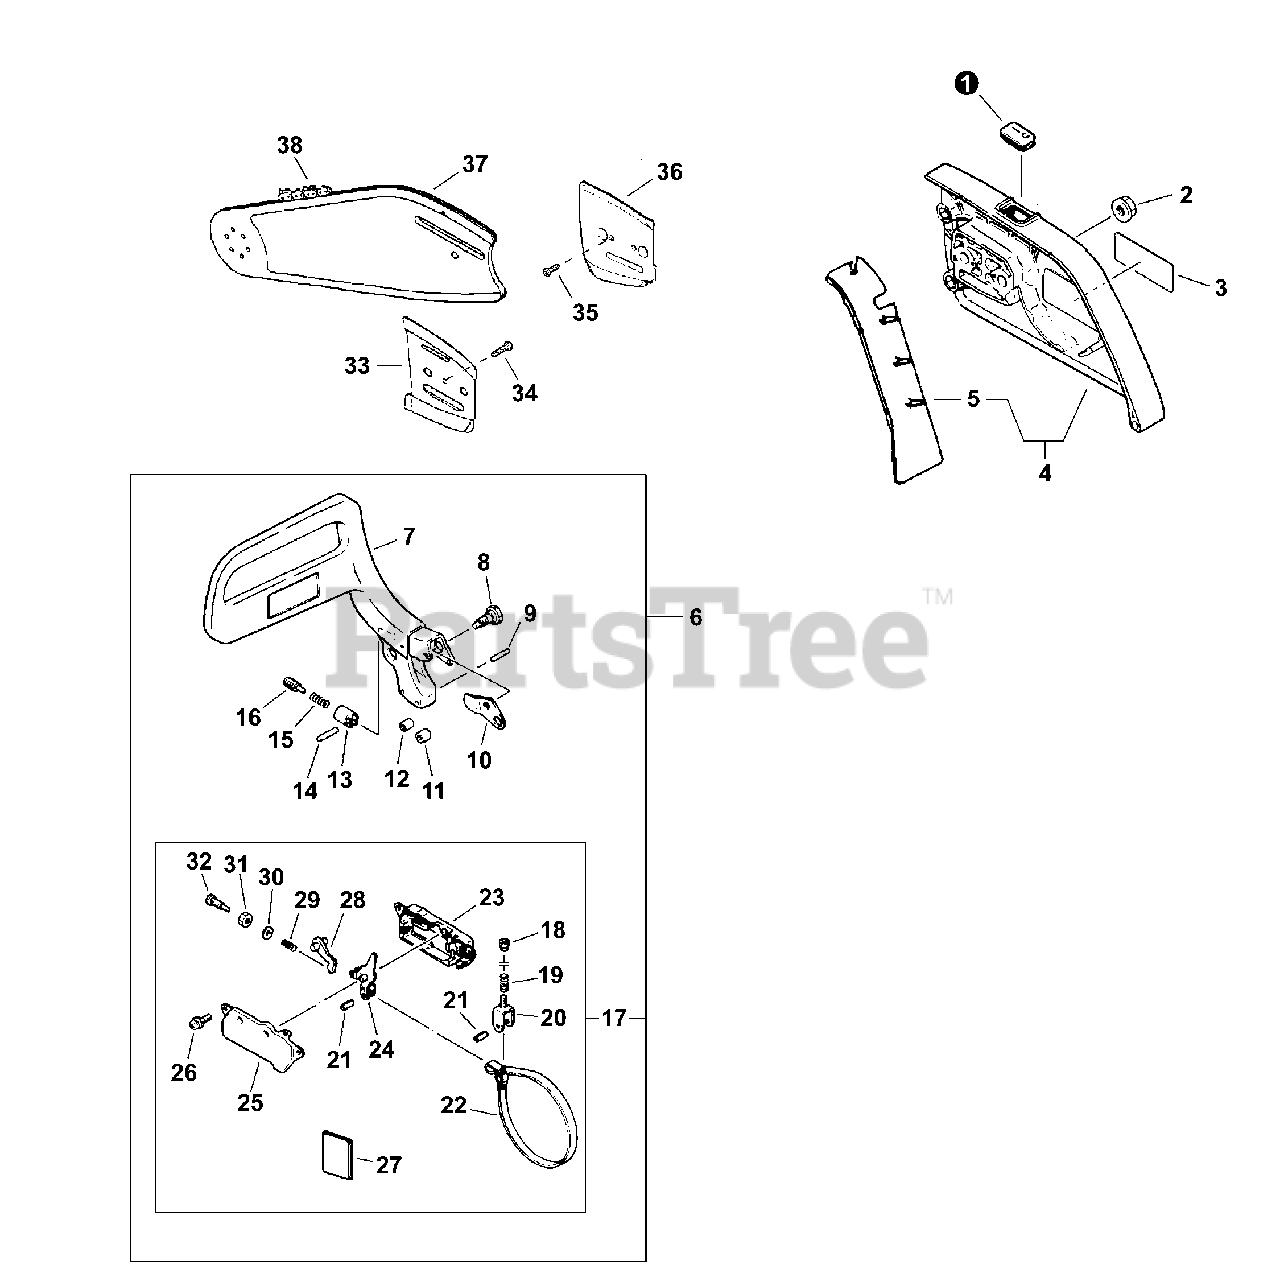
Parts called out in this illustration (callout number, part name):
1	COVER, SEAL
2	NUT, FLANGE 8
3	LABEL, ECHO
4	GUARD, SPROCKET - Gray
4	GUARD, SPROCKET - Orange
6	CHAIN BRAKE ASY
7	LEVER, BRAKE - Gray
7	LEVER, BRAKE - Orange
9	PIN 3×18
12	SPACER
14	PIN 2×20
17	CHAIN BRAKE KIT
18	NUT, ADJUSTING
20	ADJUSTER, BRAKE
21	SPRING PIN 4X10
22	BAND, BRAKE
23	COVER, BRAKE
24	LEVER, BRAKE
25	COVER, BRAKE
26	BOLT 4×10
27	SEAL, DUST
29	SPRING, WASHER
33	PLATE, GUIDE (INNER)
34	SCREW 4×8
35	SCREW 3×6
36	PLATE, GUIDE (OUTER)
37	QUIKVENT BAR
38	QUIKVENT CARBIDE CHAIN
